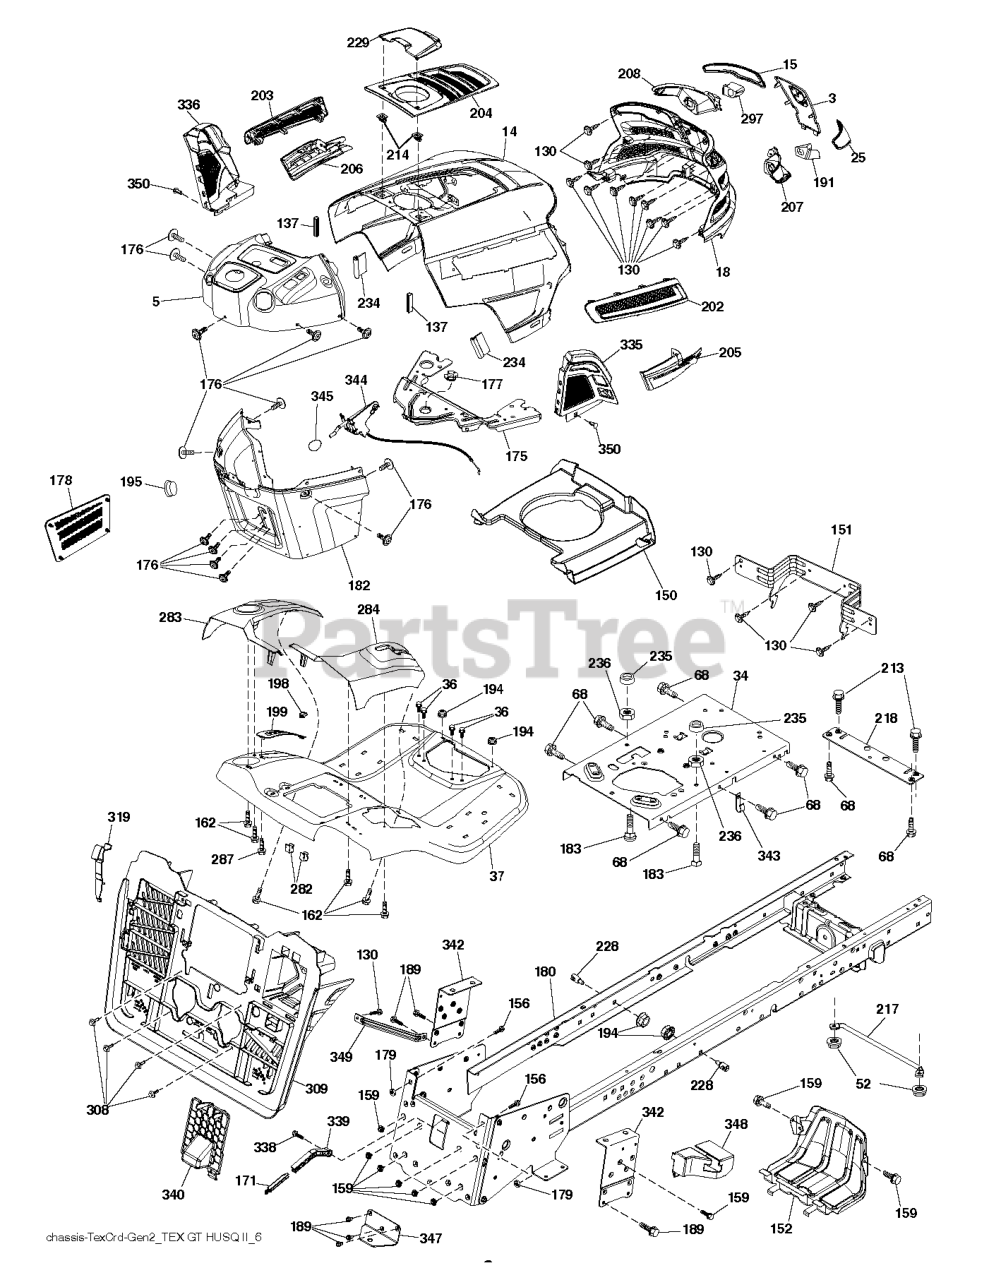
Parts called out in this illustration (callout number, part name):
3	APPLIQUE.SUBASM.GT.HUSQ.II
14	HOOD.ASM.HUSQVARNA.GT.TEX.ORAN
15	LENS.HEADLIGHT.LH.GTII.2011
18	GRILLE.SUBASM.GT.HUSQ.II
25	LENS.HEADLIGHT.RH.GTII.2011
34	PLATE PLATE ENGINE
36	SCREW 5/16"
37	FENDER.TEX.SRD.CRD.BASE
52	LOCKNUT
68	SCREW LT
130	SCREW.#10 X 0.750.BOS
137	BUMPER DASH
150	AIR.DUCT.GTV.BLACK
151	BRACKET.PIVOT.HOOD.GT.HUSQ.II
152	SHIELD.BROWNING.PNT.GT.V2
156	BOLT
159	SCREW, 3/8-16X3/4
162	SCREW.HI-LO.CONSOLE
171	EXTENSION.BAGGER.FULL.
175	PLATE.CROSSMEMBER.HUSQ
176	SCREW.#10-24X5/8.RN.QU
177	BUSHING, STEERING
178	CARGO.ASM.NET.TXGT.W/C
182	DASH DASH LOWER
183	BOLT.5/16-18X1-1/4 FULL THD
189	SCREW
191	INSERT.REFLECTIVE.RH.HUSQ.GTII
194	NUT LOCK HEX FLANGE 5/16-18
195	PLUG.HOLE.DASH.LOWER.12V.BLK
198	INDICATOR.DECK.LIFT.RED
199	PLATE DECK LIFT
202	VENT.SIDE.RH.GT.HUSQ.II.
203	VENT.SIDE.LH.GT.HUSQ.II.498
204	VENT.TOP.EXTERNAL.FILL.GT2.GRE
205	SIDE.TRIM.RH.GT.HUSQ.II
206	SIDE.TRIM.LH.GT.HUSQ.II.GRAY
207	BEZEL LIGHT.RH.GT.II.MYLAR
208	BEZEL LIGHT.LH.GT.II.MYLAR
213	BOLT
214	CLIP.RETAINER.TINNER.
217	ROD.PIVOT.HOOD
218	X-PIECE.HOOD.STOP.NON/
228	STUD.FASTNER.W/ANTI-ROTATE
229	LID.EXT.FILL.GT.HUSQ2.BLACK
234	BUMPER.HOOD.TEX.HUSQVARNA
235	SPACER FENDER
236	NUT.CENTERLOCK.5/16-
282	CLIP.RETAINER.CONSOLE.LT.HUSQ
283	CONSOLE.DECKLIFT.CRDII.498
287	SCREW 1/4X20
297	INSERT.REFLECTIVE.LH.HUSQ.GTII
308	BOLT.5/16-18UNCX3/4 W/SEMS.BLK
335	COVER.LOWER.DASH.RH.BLACK
336	COVER-LH.LOWER.DASH.GT2.BLACK
338	BOLT BOLT SHOULDER
339	LEVER.BAGGER.FULL.TEX.
342	SUPPORT SUPPORT FENDER
343	CLIP CLIP
344	CONTROL.EZ.MULCH.TEX/CRD
345	RP KNOB.OVAL.TAPERED.3/8-16BLK
347	HITCH TOW
349	BRACKET.SUPPORT.LRVB/CRD
350	CLIP.X-MAS.TREE
